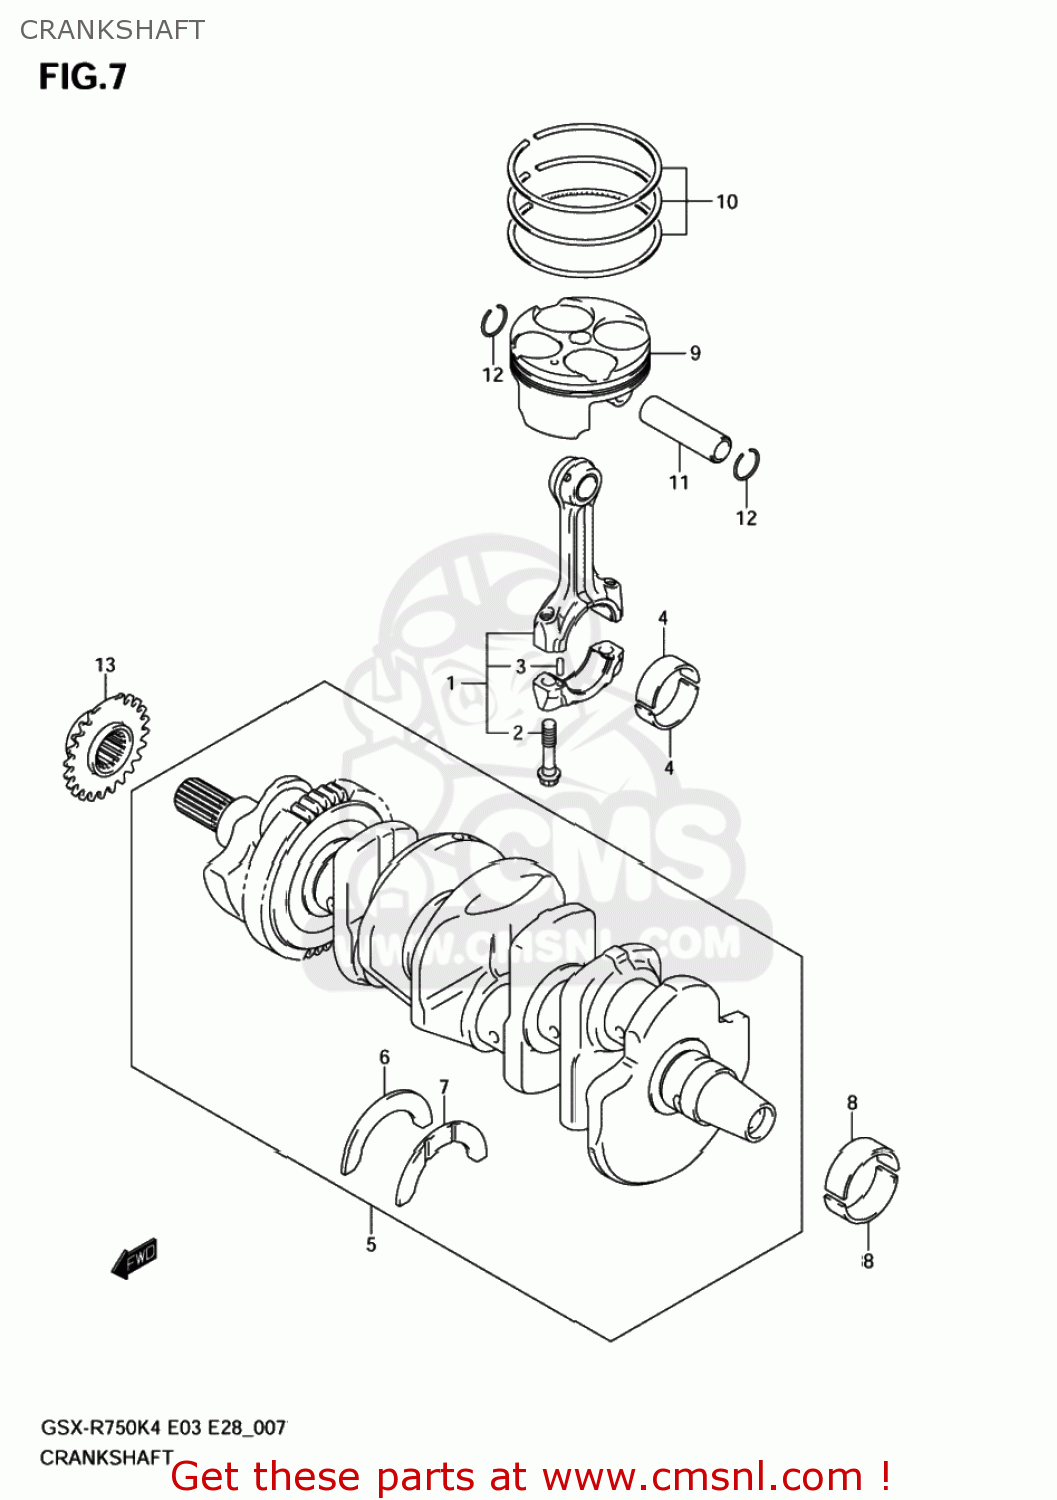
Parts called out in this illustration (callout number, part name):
1	CONNECTING ROD ASSY
2	BOLT,CONNECTING ROD
3	PIN,CONNECTING ROD
4	BEARING,CRANK PIN GREEN
5	CRANKSHAFT SET
6	BEARING,CRANK THRUST(GREEN)
7	BEARING,CRANK THRUST(RED)
8	BEARING,CRANKSHAFT
9	PISTON
10	RING SET,PISTON
11	PIN,PISTON
12	CIRCLIP
13	SPROCKET,CAM CHAIN DRIVE
